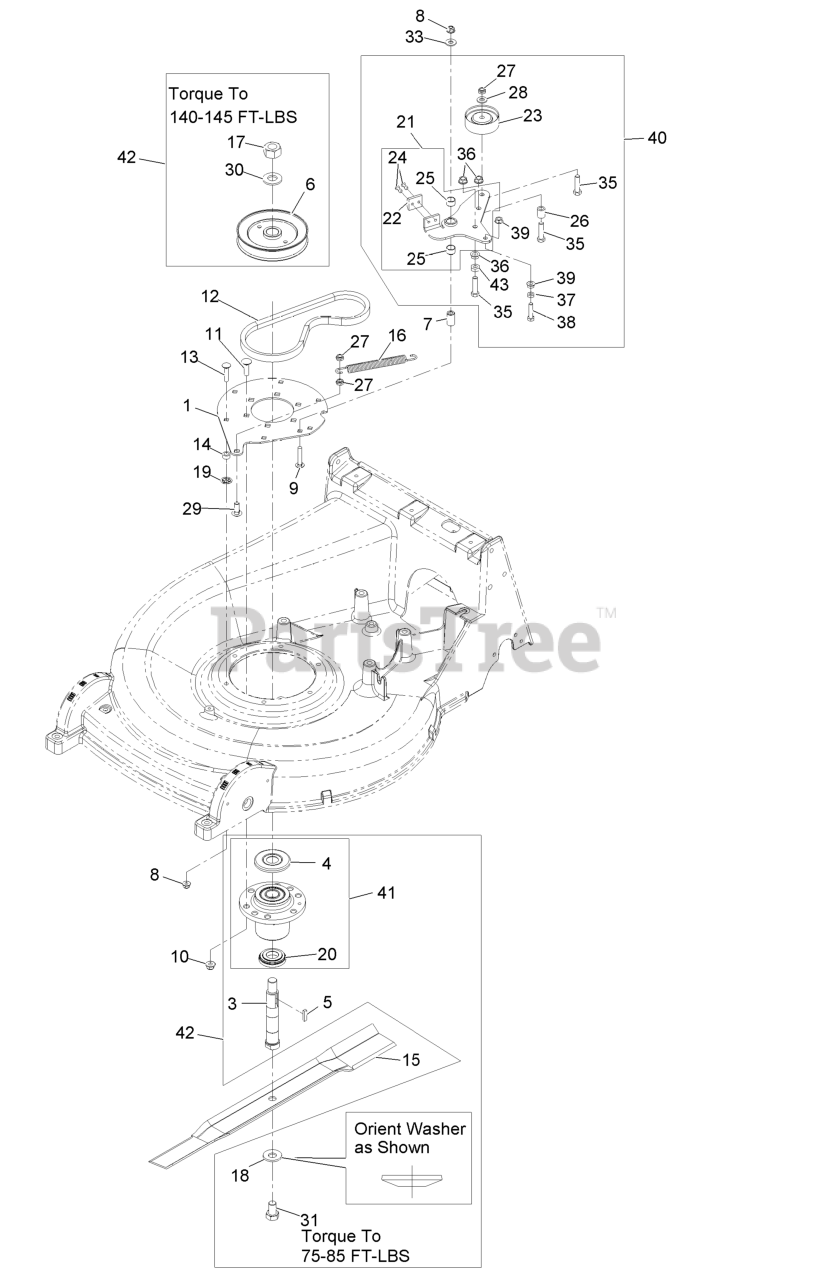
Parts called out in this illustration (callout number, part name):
1	PLATE-ADAPTER, HOUSING
3	SHAFT-SPINDLE
4	GUARD-BEARING, TOP
5	KEY-RECTANGLE
6	SHEAVE-SPLIT, STEEL (W/HU
7	BUSHING-ARM, IDLER
8	NUT-HF, NI
9	SCREW-CARR
10	NUT-HF, NI
11	Bolt-Carriage 3/8-16 X 1 1/4
12	BELT
13	BOLT-CARR
14	SPACER
15	BLADE, METRO 26
16	SPRING-BRAKE
18	WASHER-SPRING
19	RING-RETAINING
20	SPACER-GUARD, BOTTOM
21	ASM,IDLER ARM W/BSHGS
22	PAD-BRAKE
23	PULLEY-IDLER
24	RIVET-POP
25	BEARING
26	BUSHING-LEVER, LIFT
28	WASHER-FLAT
29	SCREW-CARR
31	SCREW-CAP
33	WASHER-FLAT
35	SCREW-HH
36	NUT-HHF, WHIZ
37	NUT-JAM
38	SCREW-HH
40	IDLER ARM ASM
41	KIT, CUTTER HOUSING
42	ASM,CUTTER HOUSING COMPLE
43	NUT-JAM
